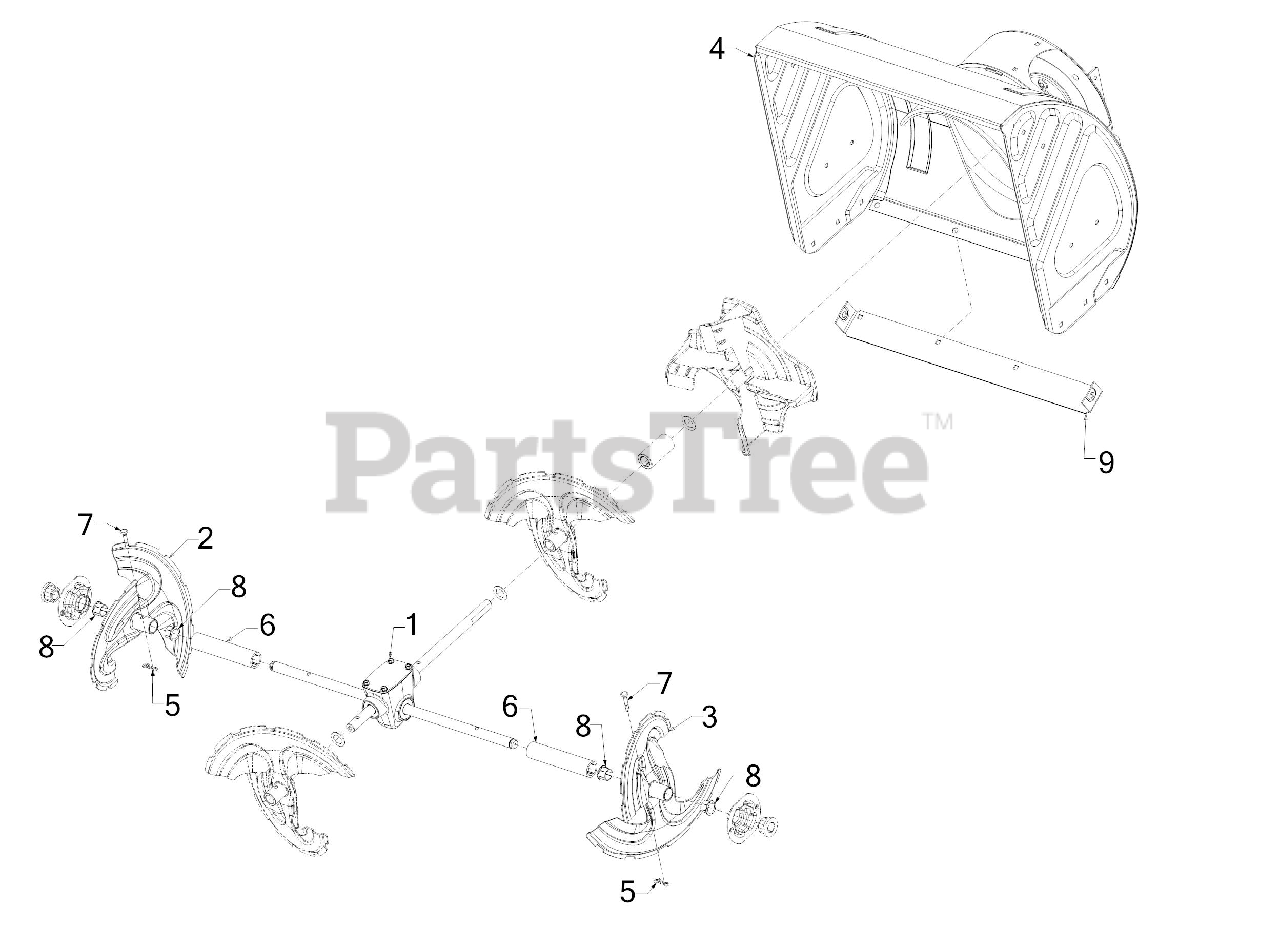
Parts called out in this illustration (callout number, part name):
1	GEARBOX ASSEMBLY 24" 3X HD
5	BOW TIE COTTER PIN 1/4-5/16
7	SHEAR PIN (.25 x 1.50)
8	FLANGE BUSHING
